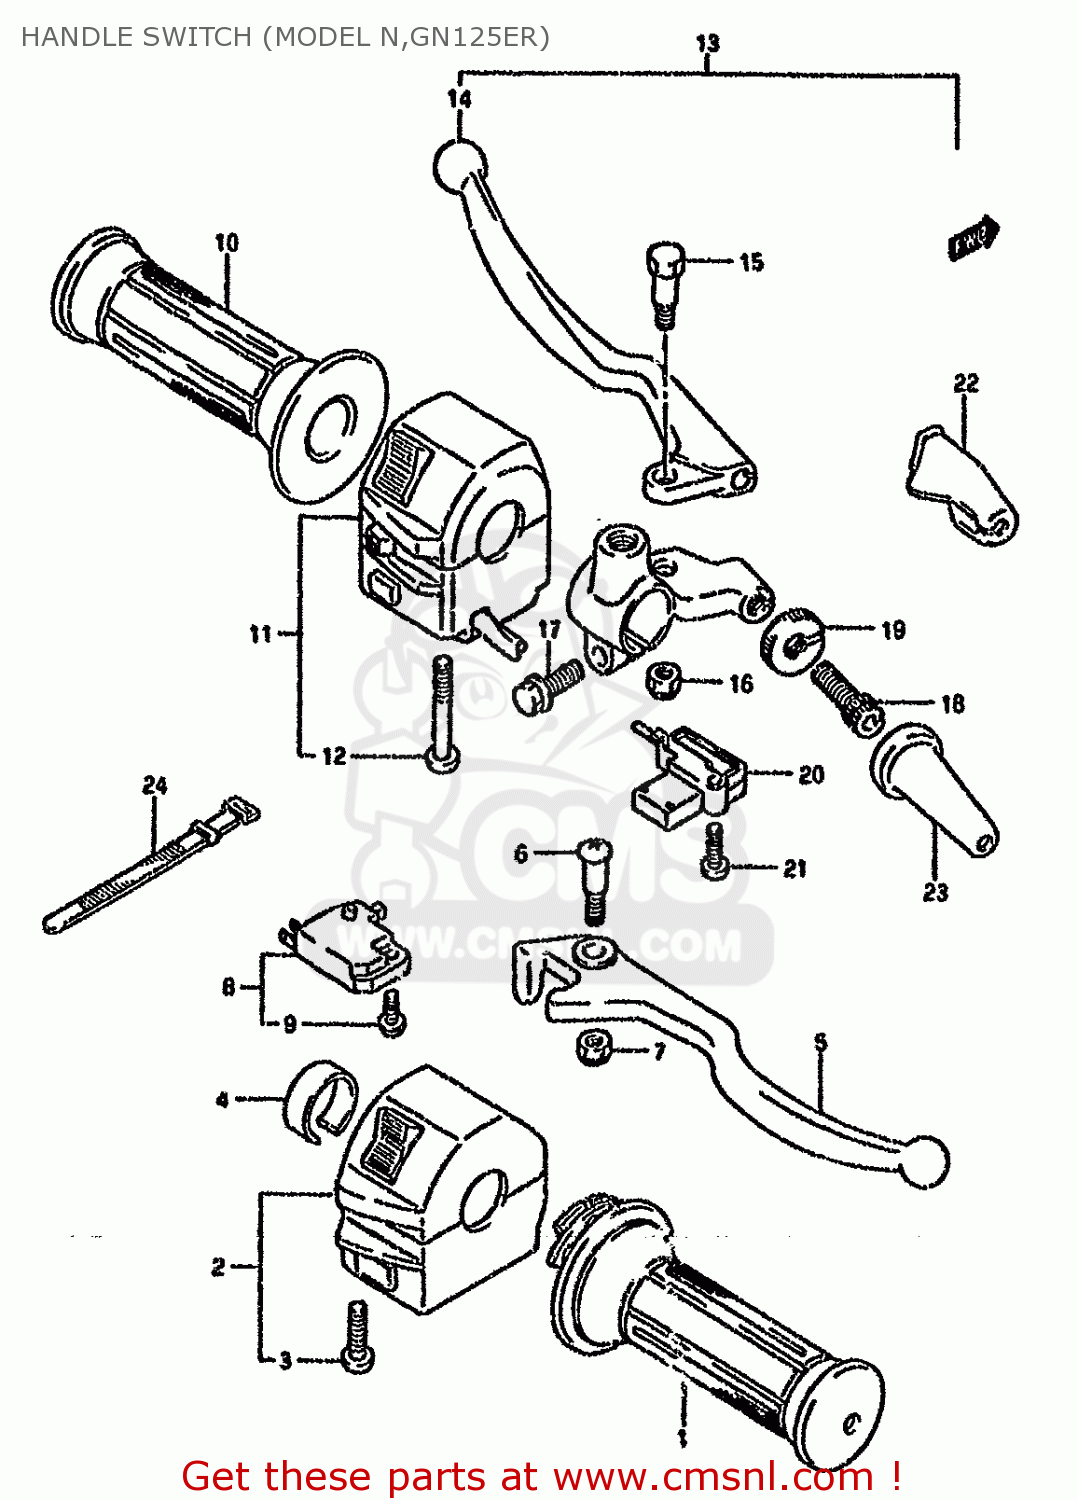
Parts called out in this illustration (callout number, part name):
1	GRIP,THROTTLE
2	SWITCH ASSEMBLY,HANDLE,RIGHT
3	SCREW 5X20
4	SPACER,HANDLE SWITCH,R
5	LEVER,BRAKE
6	SCREW,BRAKE LEVER
7	NUT
8	SWITCH ASSEMBLY,STOP
9	SCREW
10	GRIP,L
11	SWITCH ASSEMBLY,HANDLE,LEFT
12	SCREW
13	LEVER ASSY,CLUTCH
14	LEVER,CLUTCH
15	BOLT,LEVER SET
16	NUT
17	BOLT 6X20
18	ADJUSTER,WIRE
19	NUT,LOCK
20	SWITCH,CLUTCH
21	SCREW
22	COVER,CLUTCH LEVER
23	BOOT,CLUTCH CABLE
24	CLAMP(L:120)
